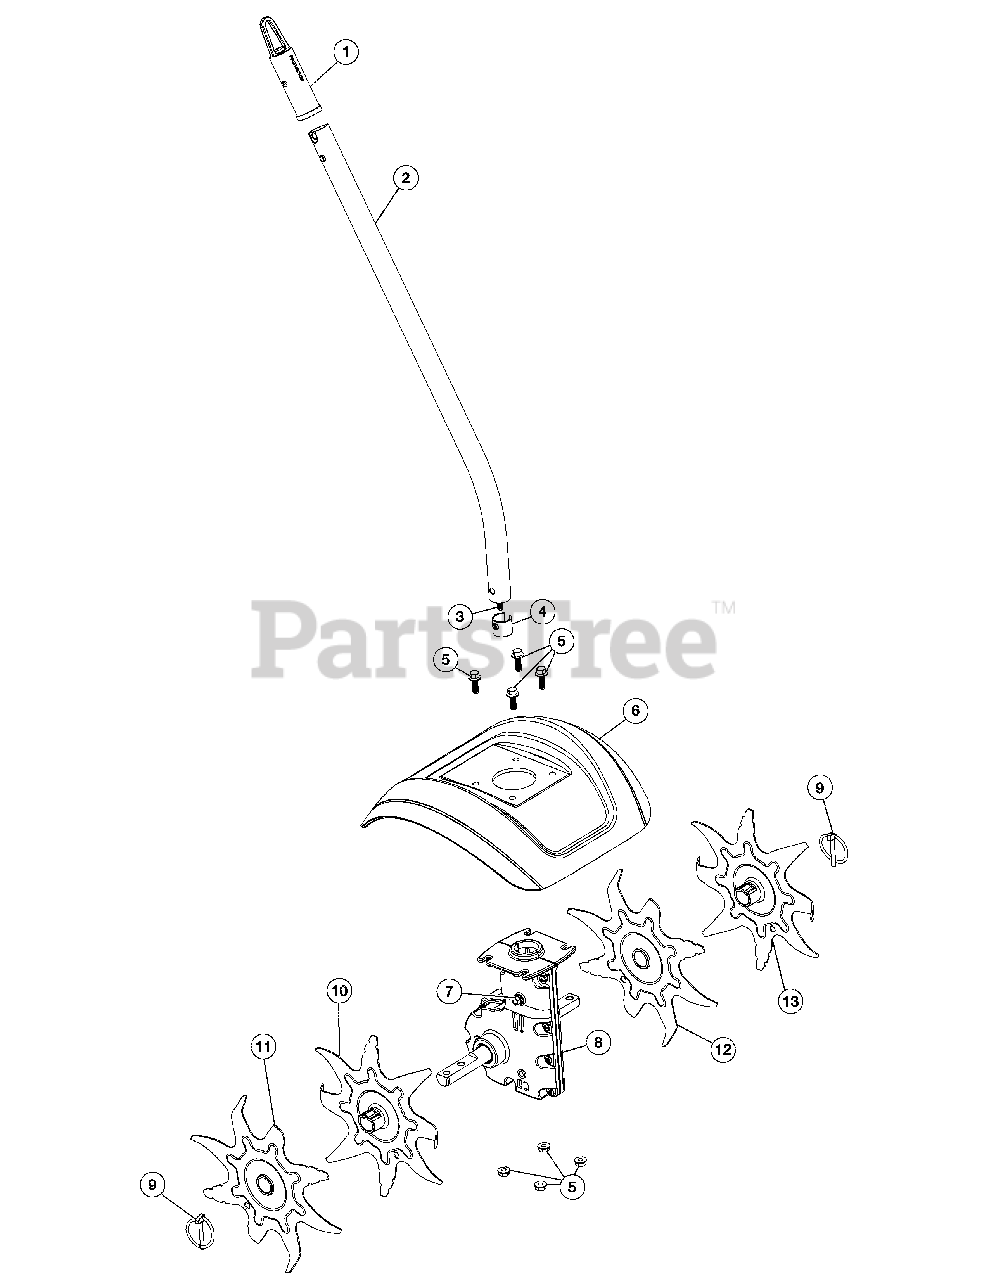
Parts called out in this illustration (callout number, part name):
1	Accessory Hanger
2	Drive Shaft Housing Assembly
3	Flexible Drive Shaft
4	Retainer Sleeve
5	Guard Mounting Hardware Set
6	Tine Shield
7	Bolt
8	Gear Box Assembly
9	Clip Pin
10	Right Inner Tine
11	Right Outer Tine
12	Left Inner Tine
13	Left Outer Tine
